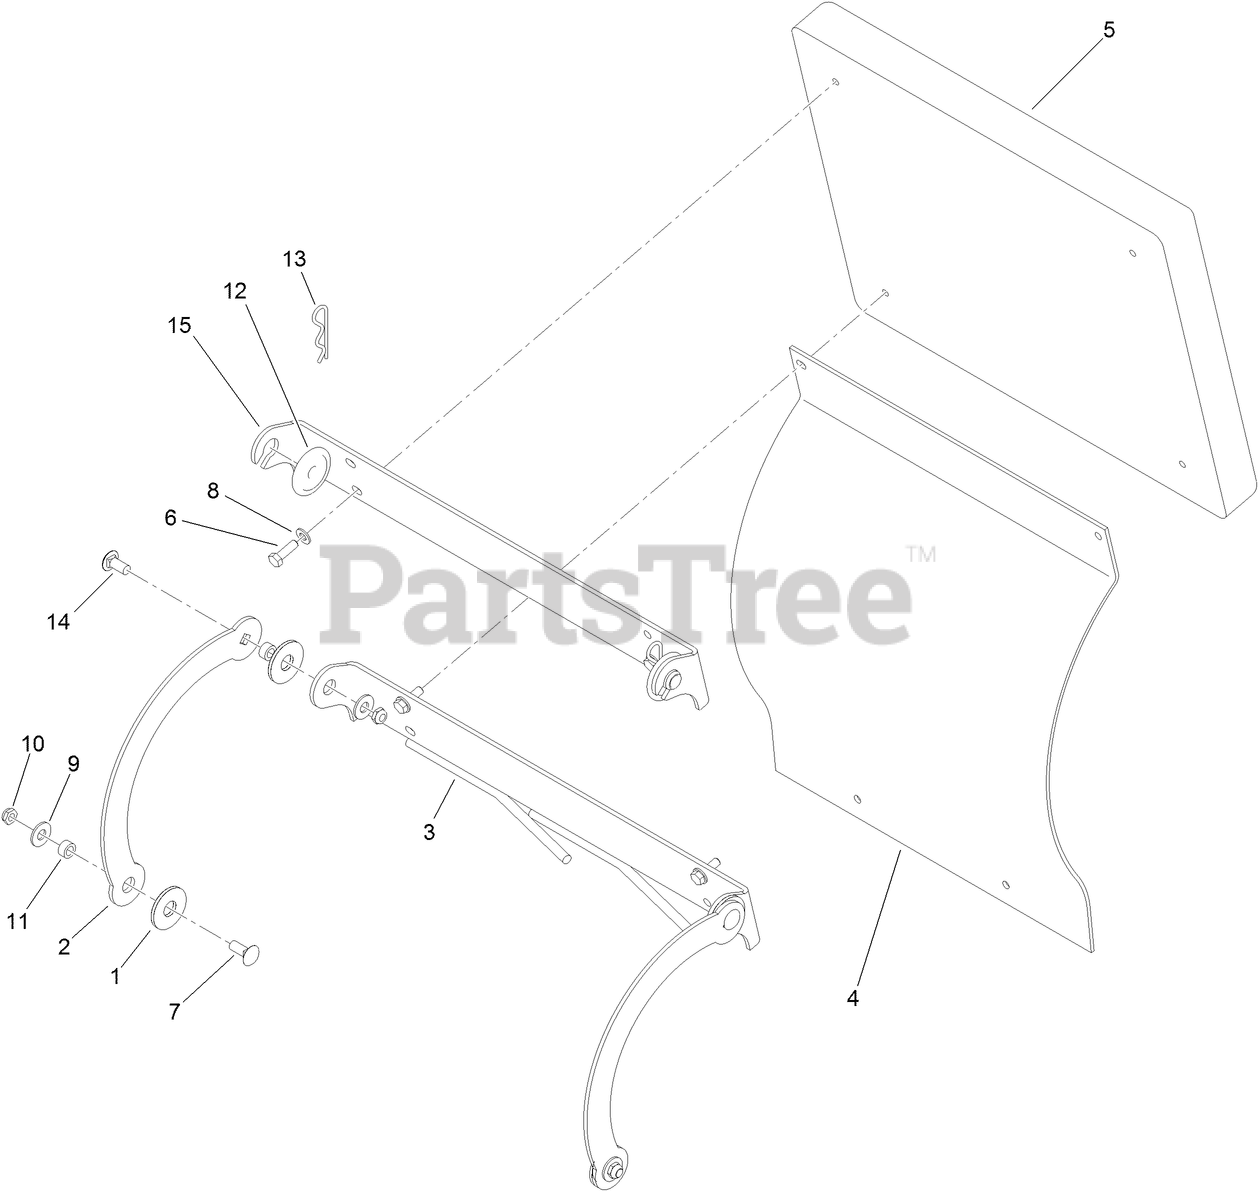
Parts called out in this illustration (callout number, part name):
1	WASHER-FRICTION, COMPOSITE
2	LINK-PAD
3	HINGE-LOWER
4	SHIELD-REAR
5	PAD-CUSHION
6	SCREW-HH
7	BOLT-CARR
8	WASHER-PLAIN
9	WASHER-FLAT
10	NUT-LOCK, NI
11	SPACER
12	SLIDE-BUSHING
13	PIN-HAIR
14	SCREW-CARR
15	HINGE-PAD
